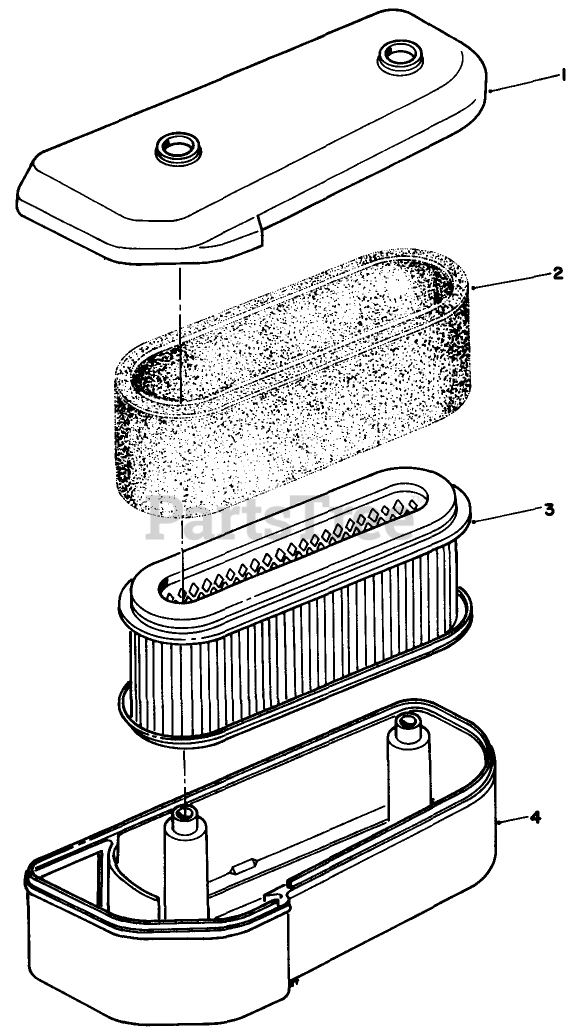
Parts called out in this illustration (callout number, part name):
1	CAP-Air Filter
2	Element
3	Element
4	CASE-Air Filter
